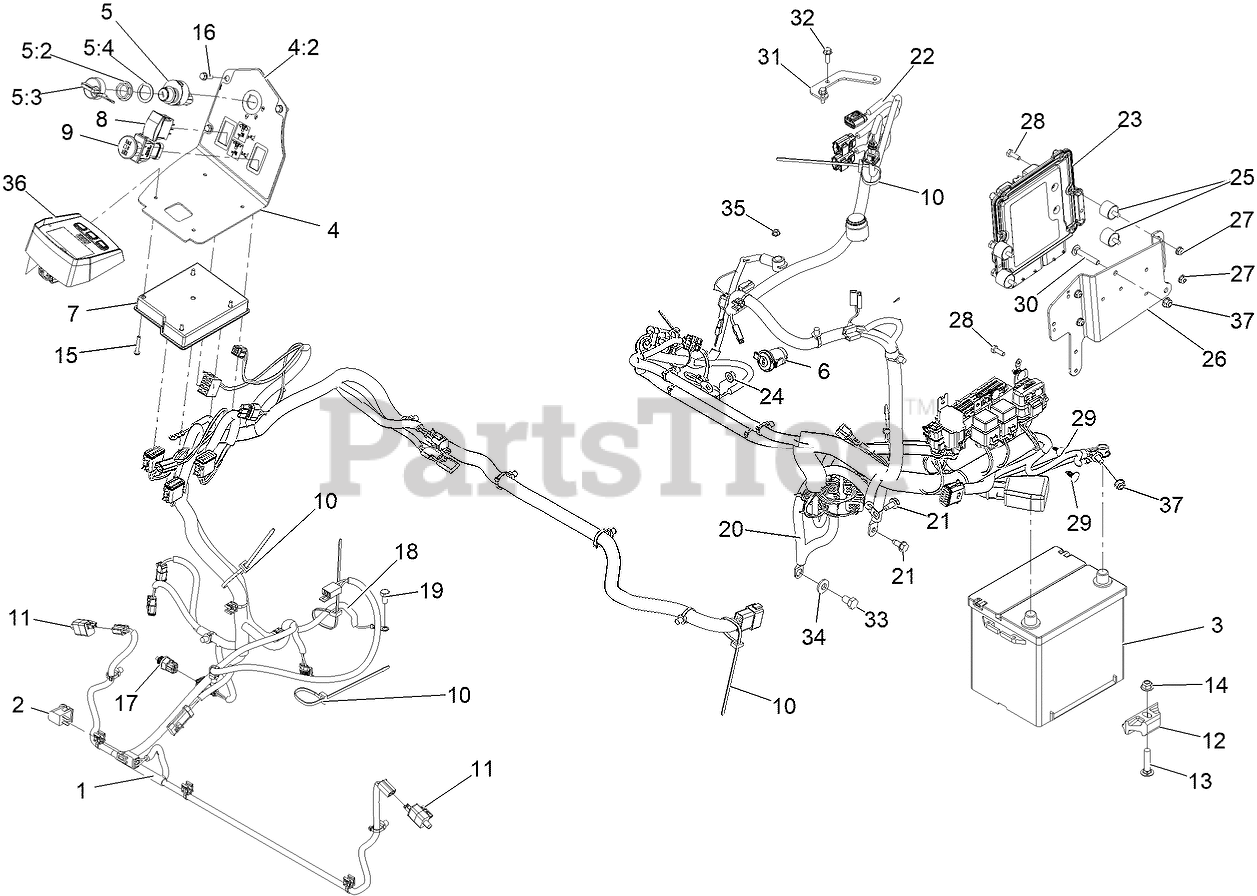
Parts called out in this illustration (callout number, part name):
1	HARNESS-WIRE
2	SWITCH-BAIL
3	Battery-Dry
4	Console ASM
4:2	DECAL-CONSOLE
5	IGNITION SWITCH ASM
5:2	NUT-MOUNTING
5:3	IGNITION KEY SET
5:4	WASHER-BACKUP
6	PORT-POWER, 12V
7	Module-Mcu
9	SWITCH-PTO, SEALED
10	TIE-CABLE
12	RETAINER-BATTERY
13	SCREW-CARR
14	NUT-HF, NI
15	SCREW-PPH
16	SCREW-HWH
17	SENSOR-TEMPERATURE
18	HARNESS-WIRE, JUMPER
19	BOLT
20	CABLE-BATTERY
21	Screw-HWH 5/16-18 X 3/4 Tf
22	Harness-Wire, Yanmar
23	Electronic Control Unit
25	MOUNT-CYLINDRICAL
26	MOUNT-CONTROL UNIT, ENGIN
28	SCREW-HH
29	PLUG-PLASTIC
30	BOLT-CARR
31	BRACKET-WIRING, ENGINE
32	SCREW-HHF
33	SCREW-HH
34	WASHER-BELLEVILLE
36	MODULE, LDU
37	NUT-HF, NI
